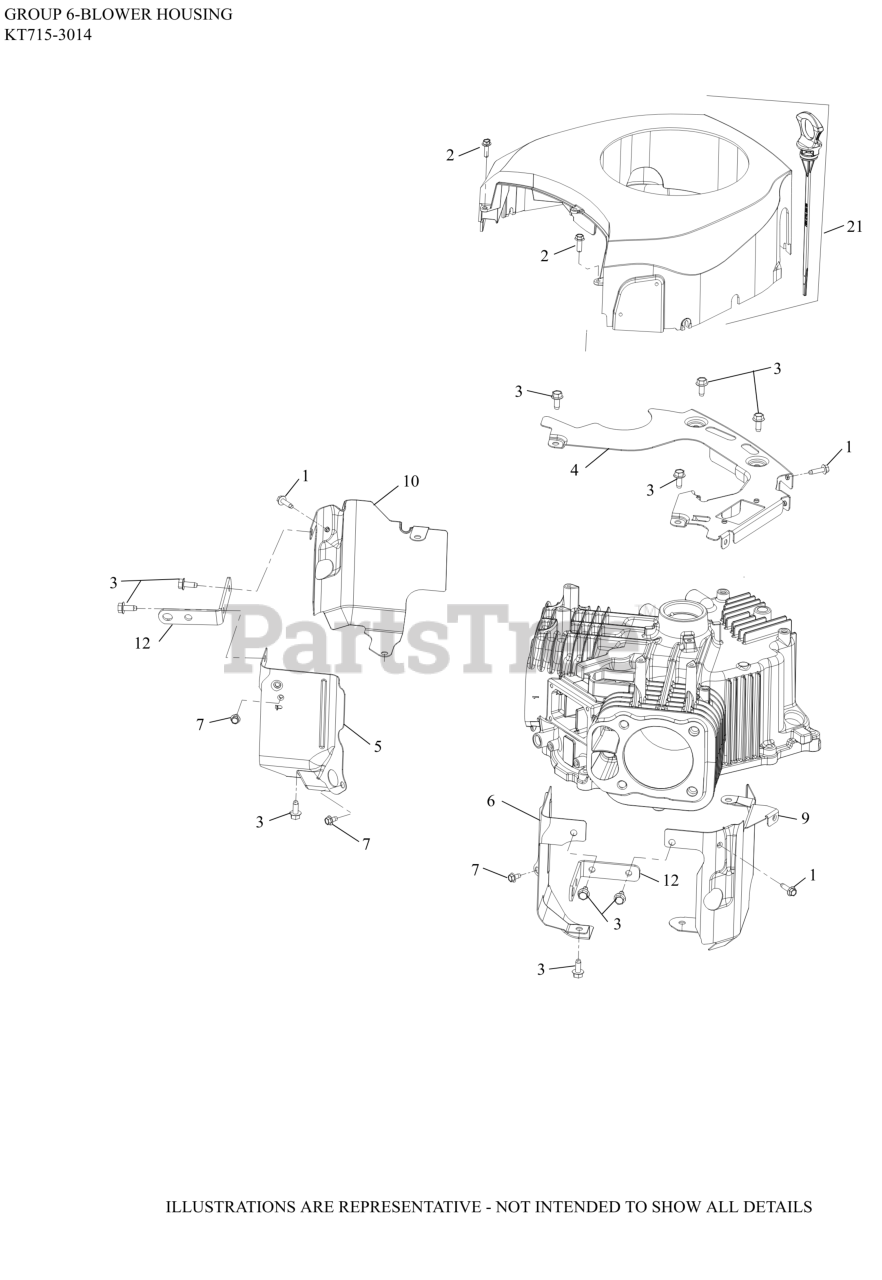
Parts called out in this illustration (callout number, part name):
1	SCREW, THD FRM-USE 25 086 473-S
2	SCREW, HI-LOW
3	SCREW, THREAD FORMING
4	PLATE, BACKING
5	BAFFLE, VALLEY #1
6	BAFFLE, VALLEY #2
7	SCREW, THREAD FORMING
9	BAFFLE, LEFT BARREL
10	BAFFLE, RIGHT BARREL
12	STRAP, LIFTING
21	KIT, BLOWER HOUSING
